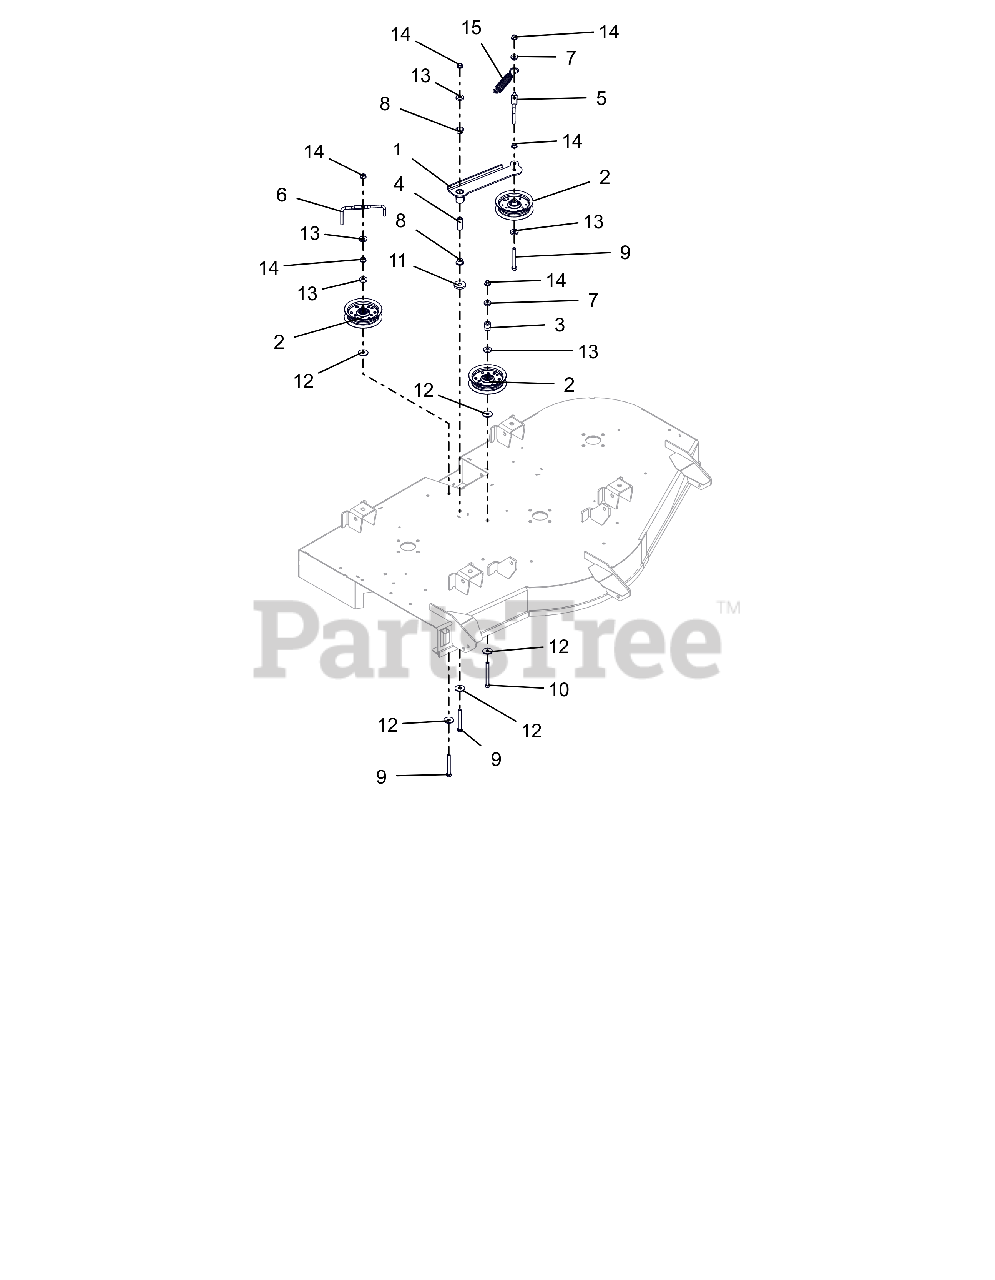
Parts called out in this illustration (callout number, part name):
1	WLDMT, IDLER ARM-52"
2	ASM, IDLER 4"
3	BUSHING, IDLER (P/M)
4	SPACER, .375IDX.625ODX1.66 PM
5	WIREFORM, BELT FINGER
6	WIREFORM, BELT FINGER
7	BSHG-FLG .385X.500X.875X.406
8	BSHG-FLG, .625X.750X.500X1.00
9	BLT-HEX .38-16X3.00 GR5 FTH YZ
10	@BLT-HEX .38-16X3.50 GR5 YWZC
11	WSHR,FLT STL.406X1.50X.245YWZC
12	WSHR FL STL .406X1.25X.10ZC120
13	WSHR-FL-STL .406X1.00X.188 YWZ
14	NUT-LK-TOP-FLG .38-16 ZC120
15	SG-TENS .135X.98X6.0 WLD 62
